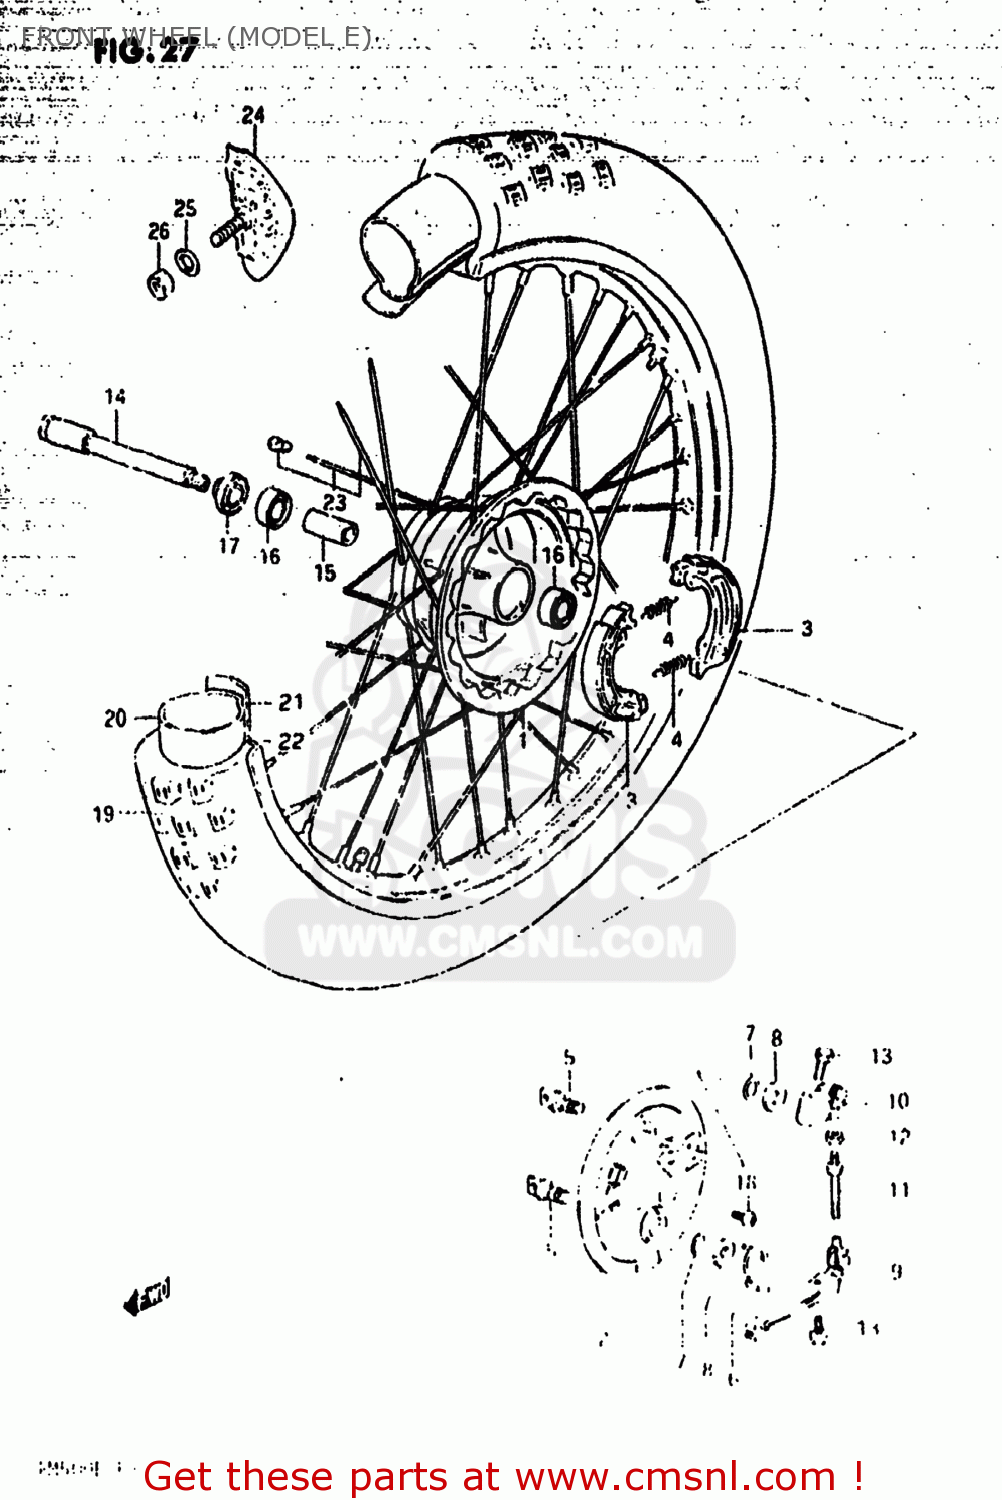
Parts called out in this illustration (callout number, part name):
1	DRUM,FRONT HUB
2	PANEL,FRONT HUB
3	SHOE,BRAKE (MCA)
4	SPRING
5	CAM,FRONT BRAKE
6	SPRING
7	O-RING (D:2 ID13.8)
8	WASHER (14.2X22X1)
9	SHOE SET,BRAKE
10	LEVER ASSY, BRAKE CAM, NO.2
11	ROD,BRAKE CAM LEVER CONNECTION
12	NUT 6MM
13	BOLT
14	AXLE,FRONT
15	SPACER,FRONT HUB BEARING
16	BALL BEARING 15X35X11
17	SPACER,FRONT AXLE,RIGHT
18	SCREW
19	TIRE,FRONT
20	TUBE,INNER
21	PROTECTOR,WHEEL,INNER
22	RIM,FRONT WHEEL (1.60X21)
23	SPOKE SET,FRONT
24	STOPPER,BEAD
25	WASHER
26	NUT 8MM
